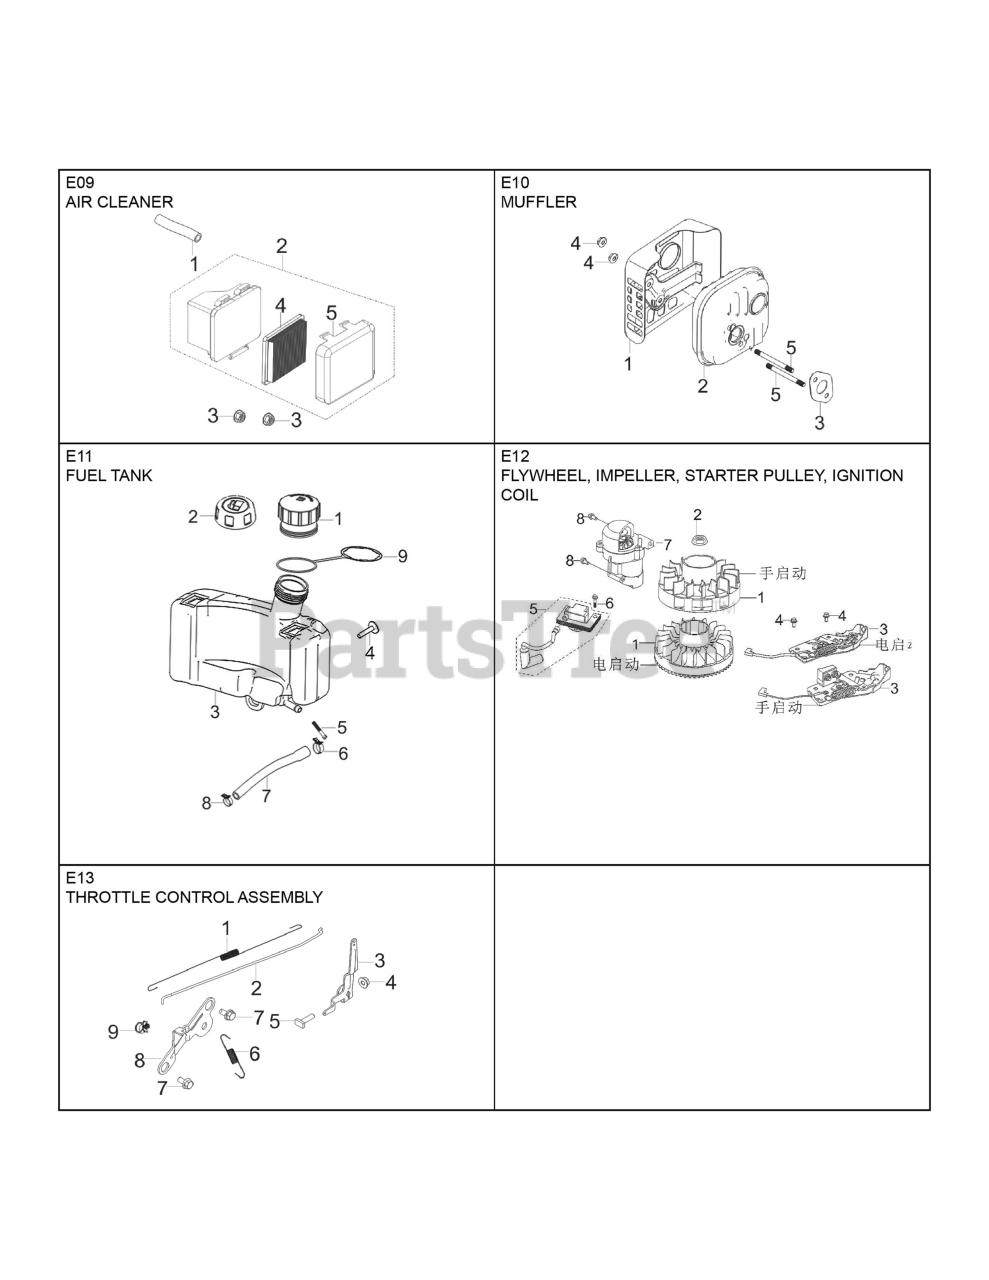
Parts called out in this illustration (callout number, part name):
2	Cleaners
E10	MUFFLER KIT RV175 MUFFLER KIT
E13	THROTTLE ASSY RV175 THROTTLE C
